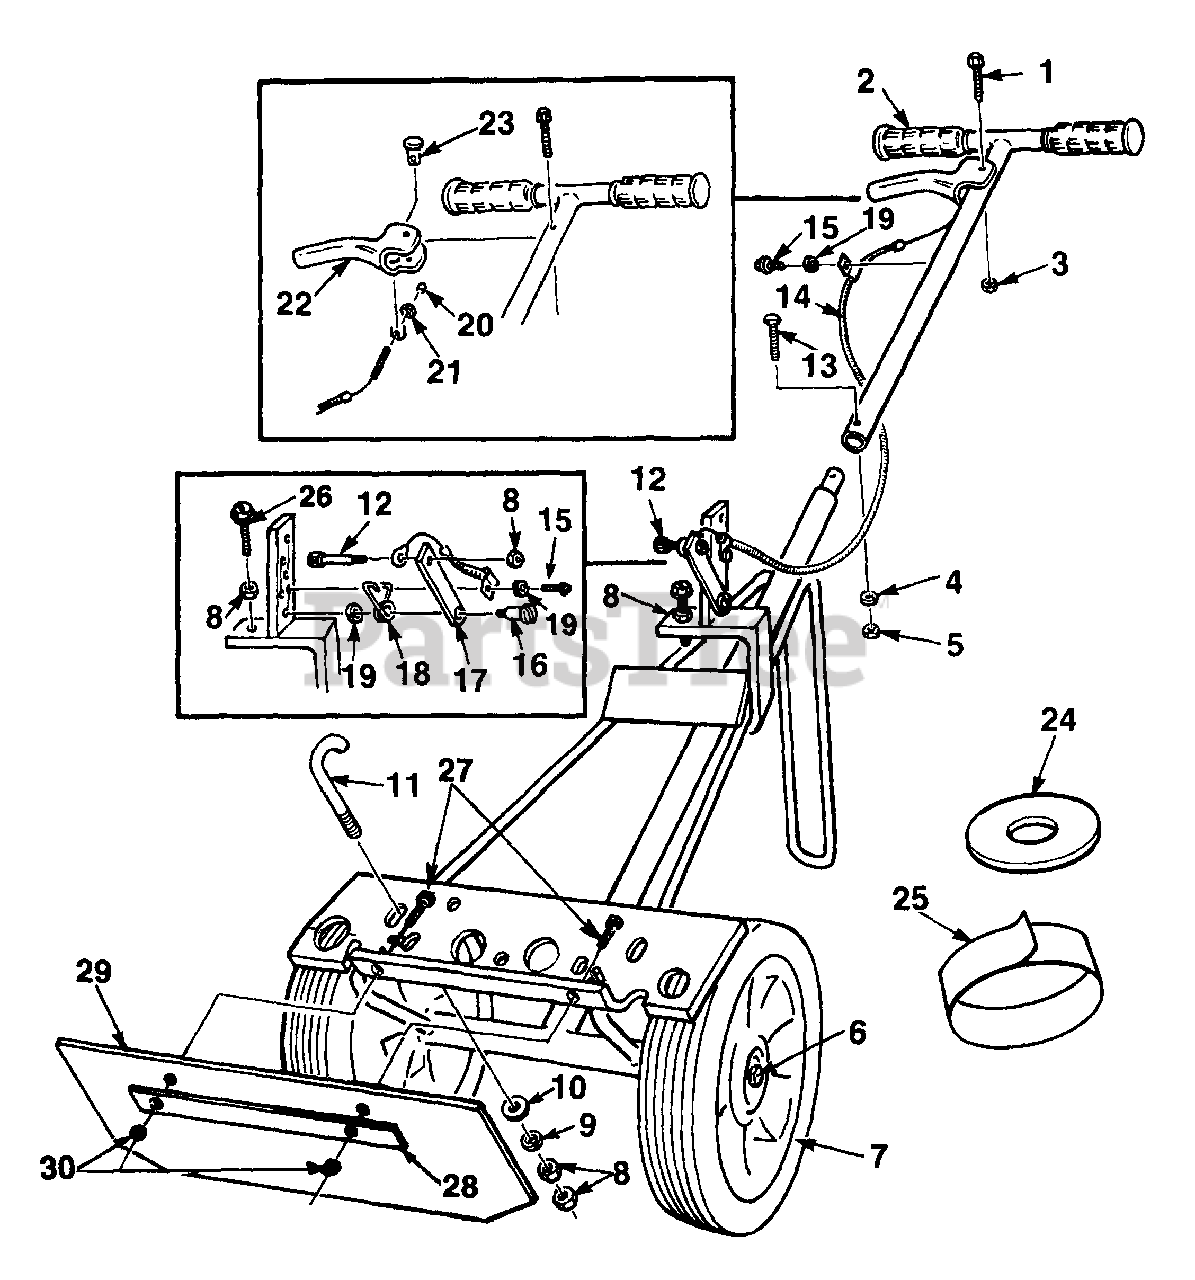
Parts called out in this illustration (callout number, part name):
1	SCREW- Hex Head (1/4-20 X 1 1/2")
2	GRIP- Handle
3	NUT- Lock (1/4-20)
4	WASHER- Lock (5/16")
5	NUT- Hex (5/16-18)
6	AXLE- Wheel
7	WHEEL/TIRE ASSEMBLY
8	NUT- Hex (1/4-20)
9	WASHER- Lock (1/4")
10	WASHER- Flat (1/4")
11	"J" BOLT
12	SCREW- Socket Head Cap (1/4-20 x 2")
13	SCREW- Hex Head (5/16 x 18 x 1 1/2")
14	CABLE- Throttle
15	SCREW- Sems Hex Head (10-32 x 3/8")
16	SCREW- Shoulder (#10-32)
17	PLATE- Trigger Lever
18	SPRING- Return
19	WASHER- Lock (#10)
21	NUT- Lock (#10-24)
22	LEVER- Throttle
24	WASHER
25	STRAP- Velcro
26	SCREW- Hex Head (1/4-20 x 1 1/2")
27	SCREW- Hex sems (8-32 x 5/8")
28	STRIP- Metal
29	SKIRT-Rubber
30	NUT- Centerlock (#8-32)
